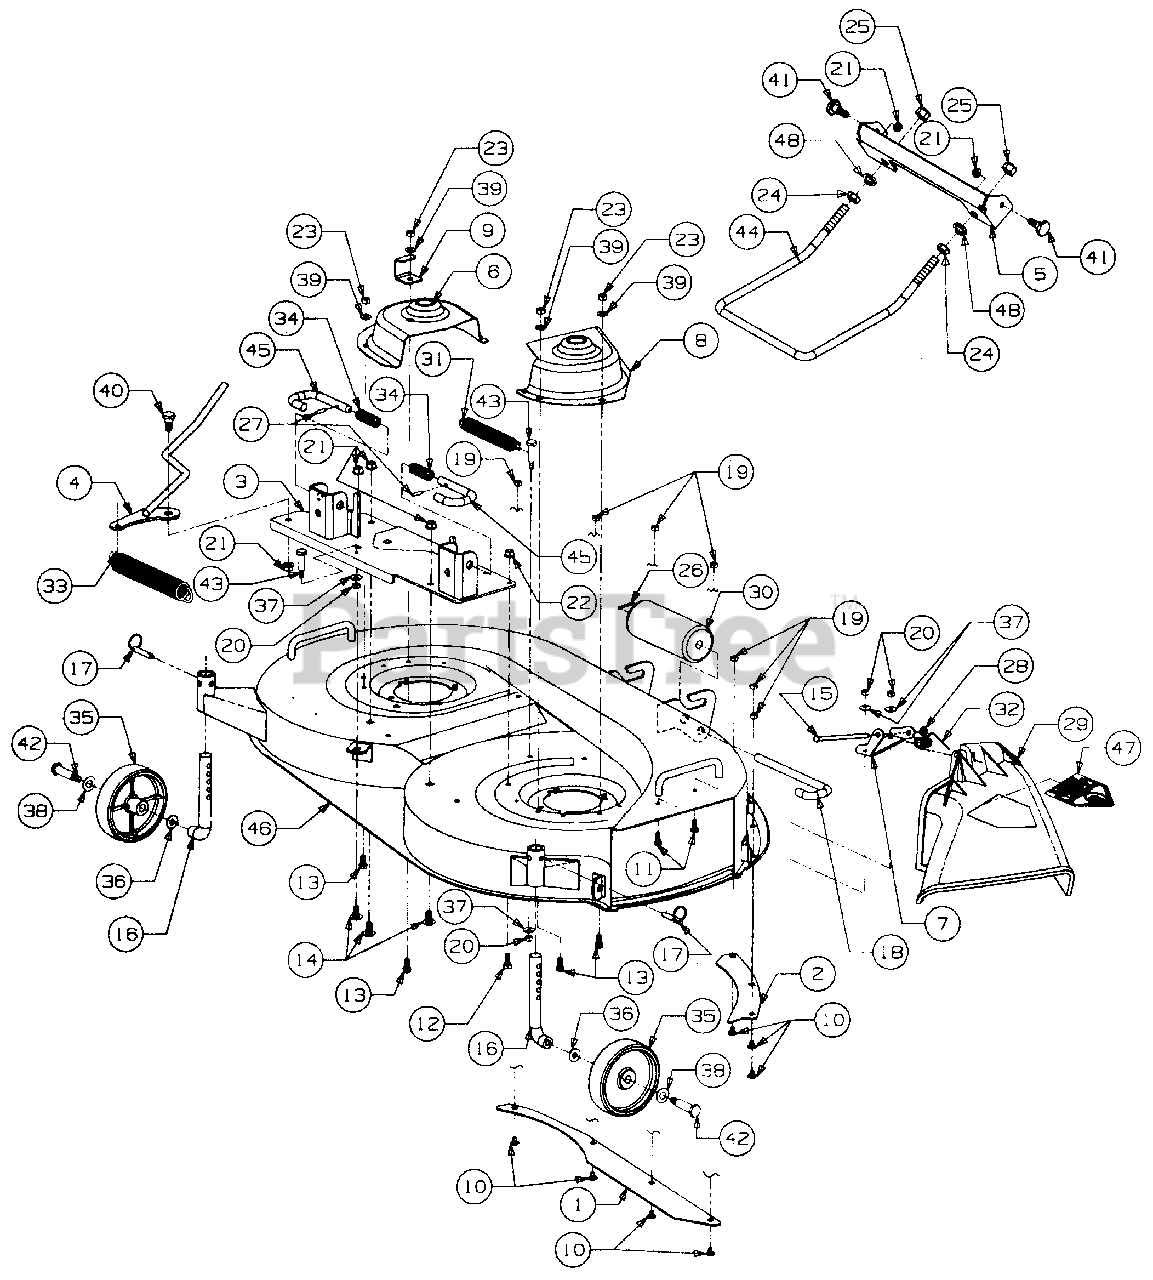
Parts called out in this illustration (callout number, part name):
1	Skirt, Extension
10	Bolt, Carriage, 1/4-20 x .50
11	Screw, Hex Cap, 1/4-20 x .62
12	Screw, Hex Cap, 5/16-18 x .75 GR5
13	Screw, Hex Cutting, 5/16-18 x .6
14	Bolt, Carriage, 3/8-16 x .75 GR5
15	Pin, Hinge, .25 Dia x 6.75 Lg
16	Axle, Deck
17	Pin, Clevis w/Ball Detent
18	Pin, Roller, 1/2 Dia x 7.31 Lg
19	Nut, Hex Sems, 1/4-20
20	Nut, Hex, 1/4-20
21	Nut, Hex Flange Lock, 3/8-16
22	Nut, Hex Flange Lock, 5/16-18
23	Nut, Hex, 5/16-18 GR5
24	Nut, Hex Jam, 1/2-13 GR5
25	Nut, Hex Insert Lock, 1/2-13
26	Pin, Cotter, 1/8 x 1.0
27	Pin Spirol Spring 3/16 x .75
28	Cap, Speed Nut
29	Deflector Assy, Chute,
31	Spring, Extension, .88 OD x 6.12
32	Spring, Torsion
33	Spring, Extension, 1.25 OD x 8.15
34	Spring, Compression
35	Wheel, Deck, 5 in. Dia
36	Washer, Bell, .380 x .88 x .062
37	Washer, Bell, .265 x .75 x .062
38	Washer, Flat, .510 x 1.0 x .060
39	Washer, Flat, .34 x .68 x .062
40	Bolt, Shoulder, .498 Dia x .340 Lg
41	Bolt, Shoulder, .50 Dia x .434 Lg
42	Bolt, Shoulder, .498 Dia x 1.64 Lg
43	Bolt, Shoulder, .375 Dia x 1.16 Lg
44	Rod, Front Lift
45	Pin, Mower Support
46	Deck Assy w/Graphics
47	Graphic, Danger
48	Washer, Lock, 1/2
